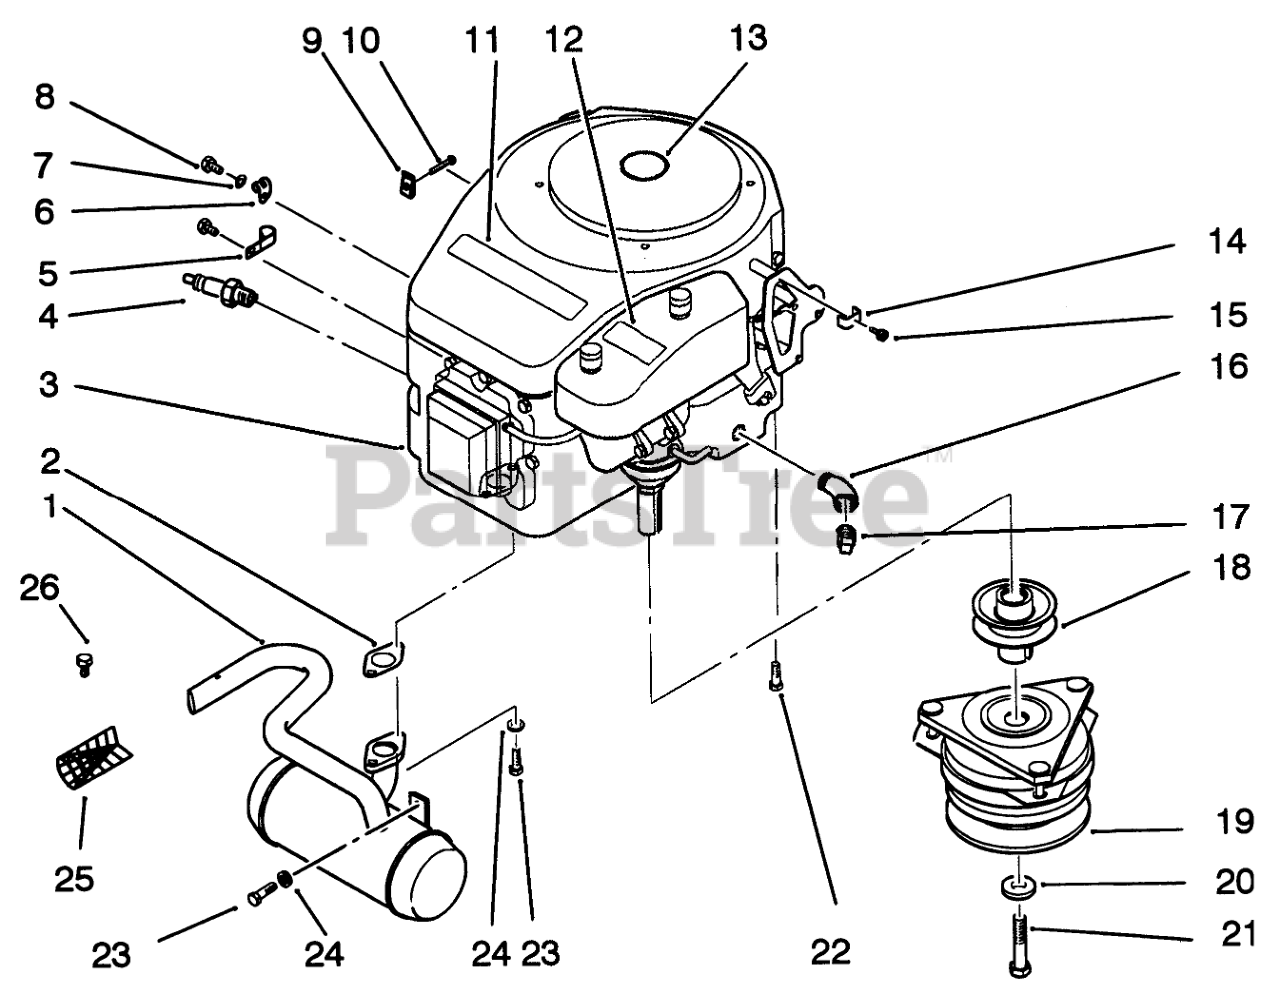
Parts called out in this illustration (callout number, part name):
1	MUFFLER
2	GASKET-EXHAUST
3	ENGINE-E14OV/11207
4	Plug-Spark
5	J-CLIP
6	CLEVIS
7	Washer
8	Screw
9	J-CLIP
10	HHCS M8X1.25X15
11	DECAL-PWR PLUS
12	DECAL-14.0 POWER PLV
13	DECAL-TORO ENGINE
14	Clamp
15	Screw
16	STREET ELBOW 45DEGRE
17	Plug
18	PULLEY-ENGINE HYD R
19	Clutch
20	WASHER
21	HHCS-M10X1.5X110 ESL
22	Bolt
23	HHCS M8X1.25X20
24	WASHER-LOCK
25	Arrester-Spark
26	BOLT-HEX S.T. #8X1/2
